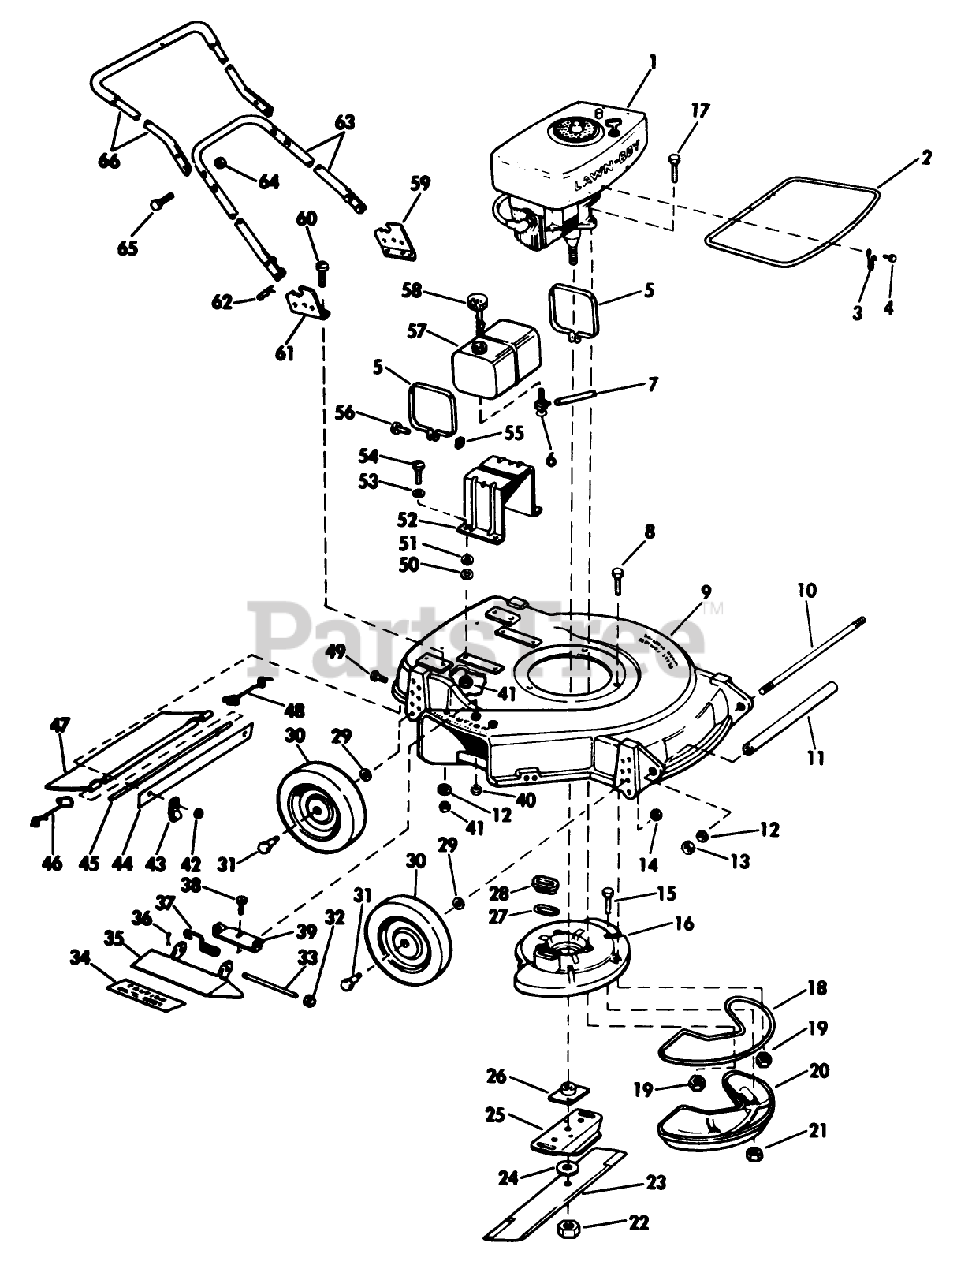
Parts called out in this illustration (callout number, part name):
1	See Page 38 for Engine, Magneto and Carburetor Parts List. See Note #2 at bottom of this page.
6	VALVE&SCREEN SM
8	SCREW
12	WASHER WROUGHT
13	LOCKNUT
14	NUT
15	SCREW
19	NUT-LOCK F
22	NUT-BLADE
24	WASHER
26	PLATE AND COLLAR ASM
27	GASKET S
28	SLEEVE
29	WASHER, LOCK
33	HINGE PIN
36	Cotter Pin
38	Screw
40	LOCKNUT E
41	LOCKNUT E
42	LOCKNUT E
46	SPRING;TRAILING SHIELD RH
48	SPRIG T/SHLD ASOC
49	Screw
50	WASHER
54	BOLT PIONEER
55	Nut
60	SCREW S
65	SCREW
